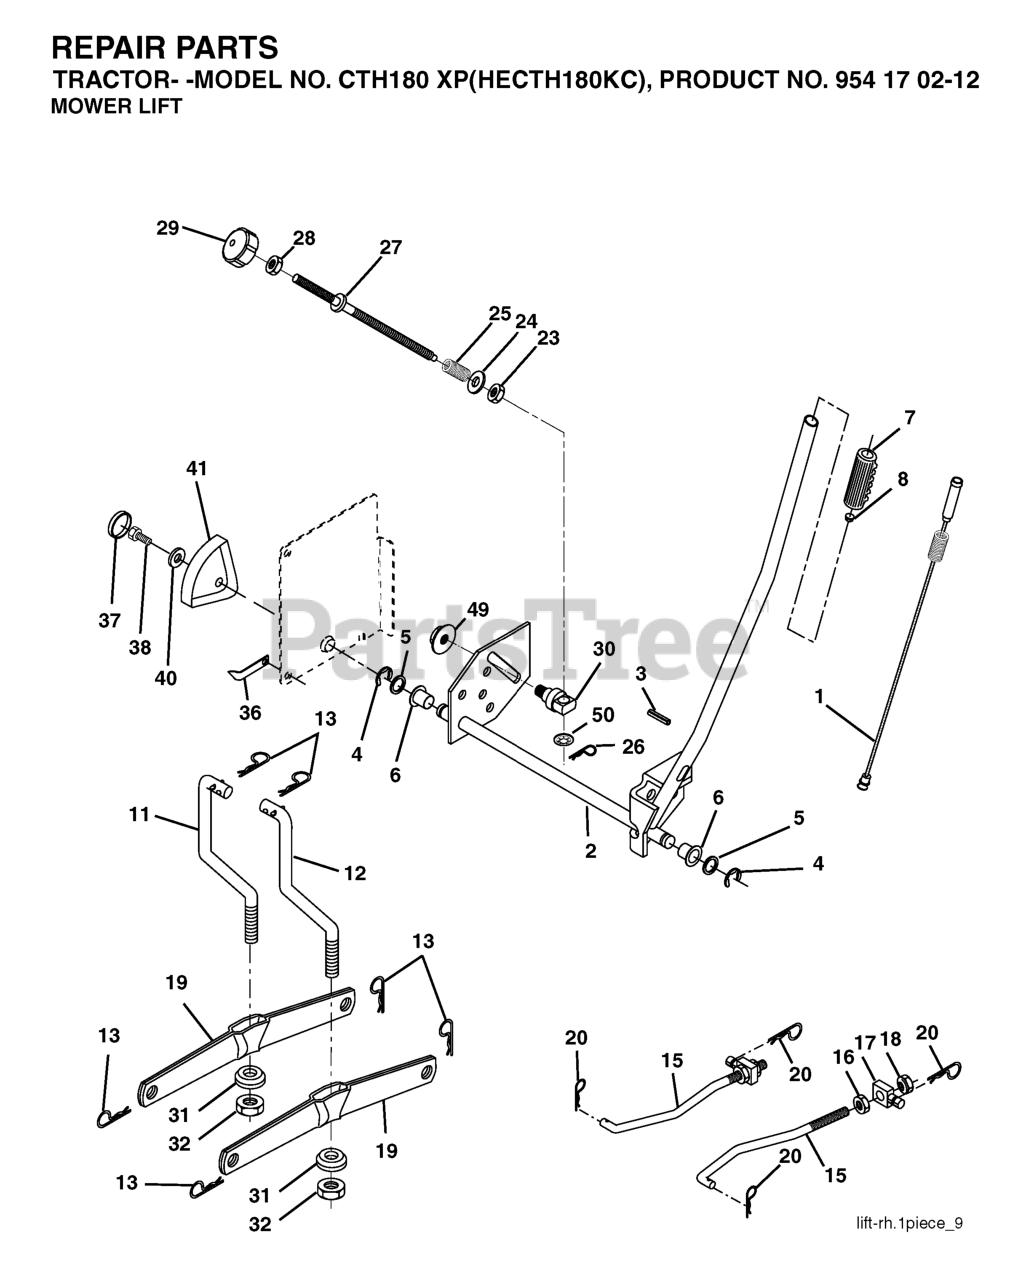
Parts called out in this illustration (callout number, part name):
1	WIRE ASM INNER W/ PLUNGER LT
2	SHAFT ASM R HANDLE
3	PIN GROOVE.
4	RETAINING RING LT
6	BEARING.NYLON
7	GRIP HANDLE
8	PLUNGER BUT KIT
11	LINK
12	LINK
13	RETAINER-SPRNG RB
15	LINK.SUSPENSION.FRONT
16	NUT.HEX.JAM.1/2-13
18	NUT.LK.W/WSH.1/2.
19	ARM.REAR.SUSPENSION
20	SPRING RETAINER
25	SPRING**
26	RETAINER CLIP
27	ROD ADJ LIFT
28	NUT
29	KNOB INF 3/8-16
31	BEARING.PIVOT.LIFT
32	NUT CROWNLOCK 3/8-24
36	POINTER, HEIGHT INDICATOR(2 2)
38	SCREW 5/16-18X1
41	HEIGHT INDICATOR
49	NUT
50	NUT PUSH M
